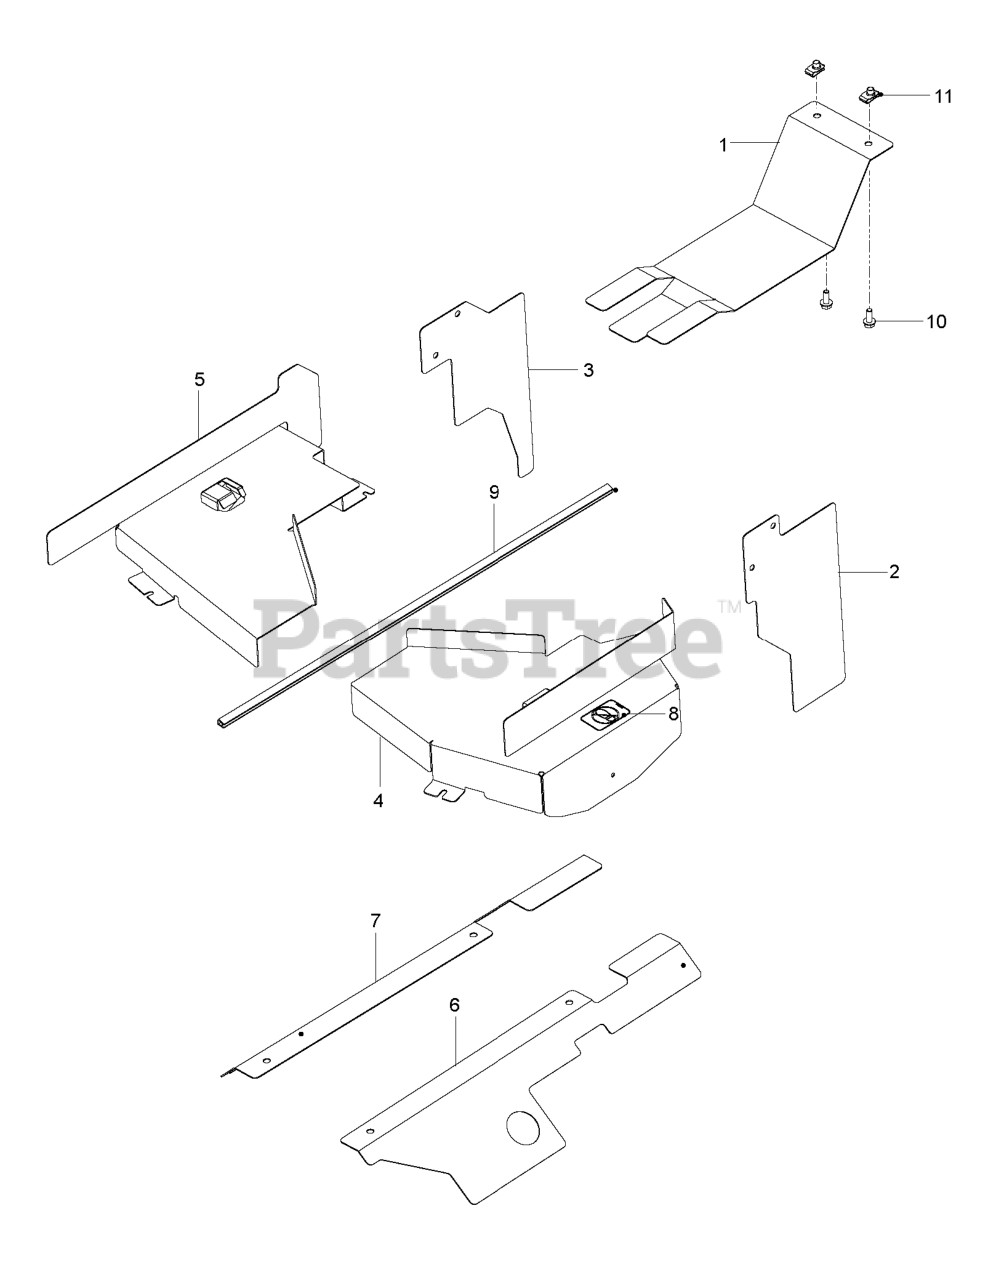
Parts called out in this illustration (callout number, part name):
1	GUARD REAR
2	GUARD.FLAT.WALL.LEFT.BLACK
3	GUARD.FLAT.WALL.RIGHT.BLACK
4	GUARD BELT COVER LT
5	GUARD BELT COVER RT
6	GUARD.ANGLED.WALL.LEFT.BLACK
7	GUARD ANGLED WALL RT
8	DECAL, NO STEP
9	RP.FLEX TRIM, BLK-LENGTH 1 FT
10	HHFS 5/16-18 X 3/4
11	U-CLIP 5/16-18 NUT RETAINER
